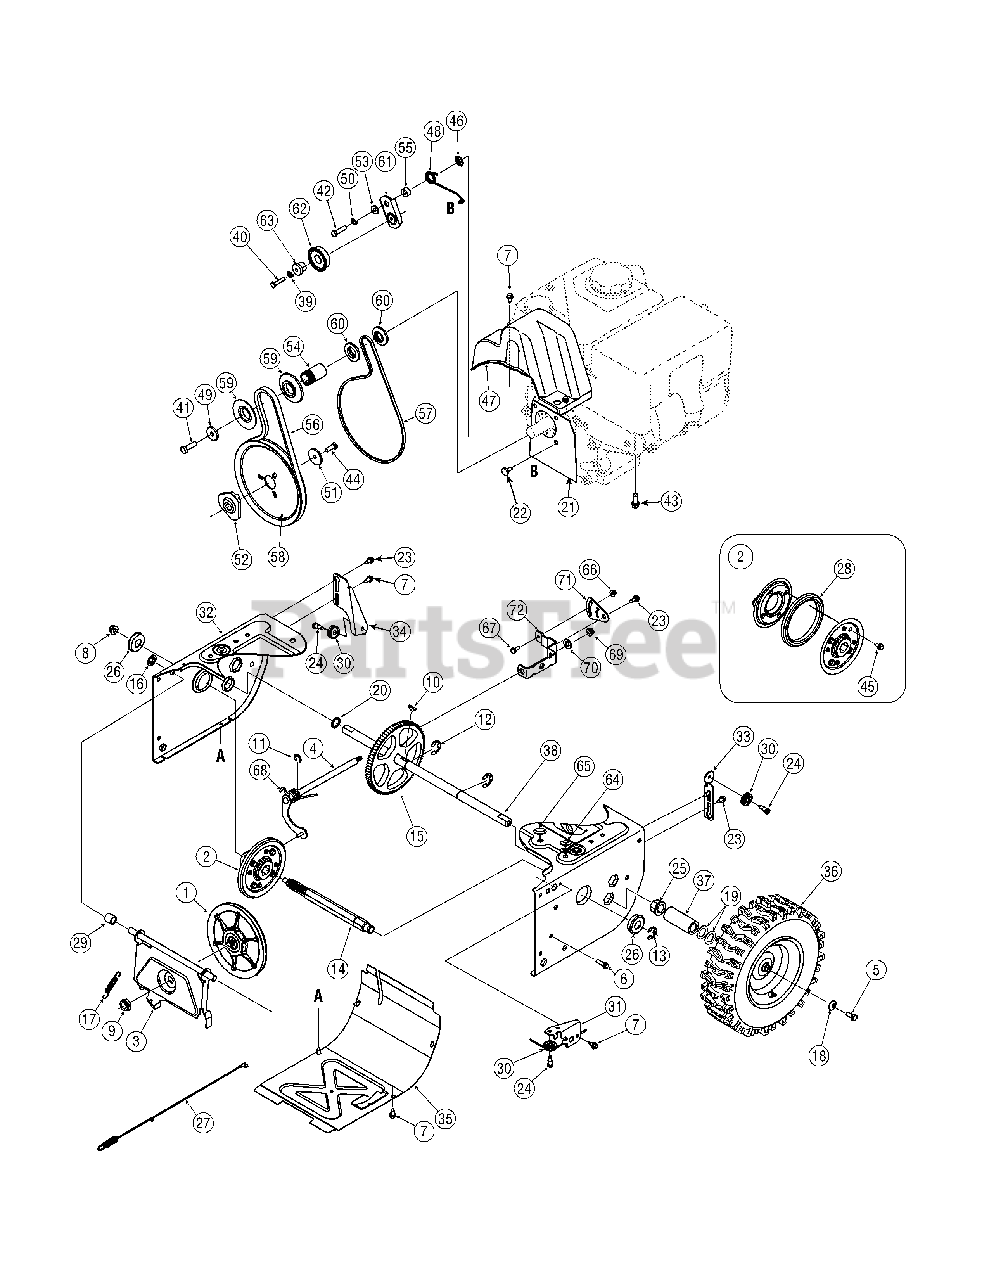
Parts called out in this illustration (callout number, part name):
1	Disc Assembly, Friction Wheel
2	Friction Wheel Assembly, 5.5 OD
3	Support Bracket, Friction Wheel
4	Shift Assembly, Rod
5	Hex Screw, 5/16-24, .750, Gr5
6	Screw, 1/4-20, 1.000
7	Screw, 1/4-20 x .625
8	Nut, Flange Lock, 3/8-16, Nylon
9	Nut, Flange, 5/8-18
10	Key, Hi Pro, 3/16 x 3/4 Dia.
11	E-ring, .500 Dia.
12	E-ring, Retaining, .875 Dia.
13	E-ring, .750 Dia.
14	Hex Shaft, .8125, 7-Tooth
15	Gear, 80-Tooth
16	Speed Nut, .500
17	Extension Spring
18	Washer, Bell, .340 x .872 x .060
19	Washer, Flat, .793 x 1.24 x .060
20	Washer, Flat, .75 x 1.00 x .060
21	Plate, Cover
22	Shoulder Screw
23	Screw, Shoulder, .37 x .105, 1/4-20
24	Screw, 1/4-28, .375
25	Bearing, Hex Flange x .75 ID
26	Bearing, Ball, 17 x 40 x 12
27	Clutch Cable, Wheel, 44.95"
28	Rubber, Friction Wheel, 5.5 OD
29	Spacer, .508 ID x .75 OD x .68
30	Roller, Cable
31	Front Guide Bracket, Auger Cable
32	Frame
33	Guide Bracket, Auger Cable
34	Guide Bracket, Drive Cable
35	Cover, Frame
36	LH Wheel Assembly
36	RH Wheel Assembly
37	Spacer, 1.25 x .75 x 3.0
38	Axle, .75 x 22"
39	Washer, Lock, 1/4
40	Hex Screw, 1/4-20, 1.25, Gr5
41	Hex Screw, 3/8-24, 1.25, Gr8
42	Hex Screw, 5/16-24, 1.25, Gr5
43	Screw, Sems, 3/8-16, 1.00
44	Hex Screw, 5/16-24, .875, Gr8
45	Screw, 1/4-20 x .625
46	Nut, Push-on, .25 Dia.
47	Cover, Belt
48	Spring, Torsion, .850 ID x .354
49	Washer, Flat, .406 x 1.25 x .157
50	Washer, Lock .3125
51	Washer, Flat, .34 x 1.50 x .150
52	Pulley, Adapter, .75 Dia.
53	Spacer, Shoulder, .317 x .50 x .102
54	Spacer, .875 ID x 1.185 OD
55	Spacer, .340 x .750 x .360
56	Belt, Auger Drive
57	Belt, Wheel Drive
58	Pulley, Auger Drive, 8.1 x .5
59	Pulley, Half, V x 2.600 OD
60	Pulley, Half, 3/8-V x 1.7160 OD
61	Idler Bracket, Wheel Drive
62	Idler Pulley Assembly
63	Spacer, Shoulder, .26 x .79 x .538
64	Plug, 3/8 ID
65	Plug, 1/2 ID
66	Nut, Flange Lock, 1/4-20, Nylon
67	Hex Screw, 1/4-20, .620, Gr5
68	Spring, Torsion, .750 ID x .968
69	Nut, Flange Lock, 5/16-18, Nylon
70	Wash., Flat, .469 x .875 x .105
71	Pivot Bracket, Speed Selector
72	Shift Bracket, Speed Selector
